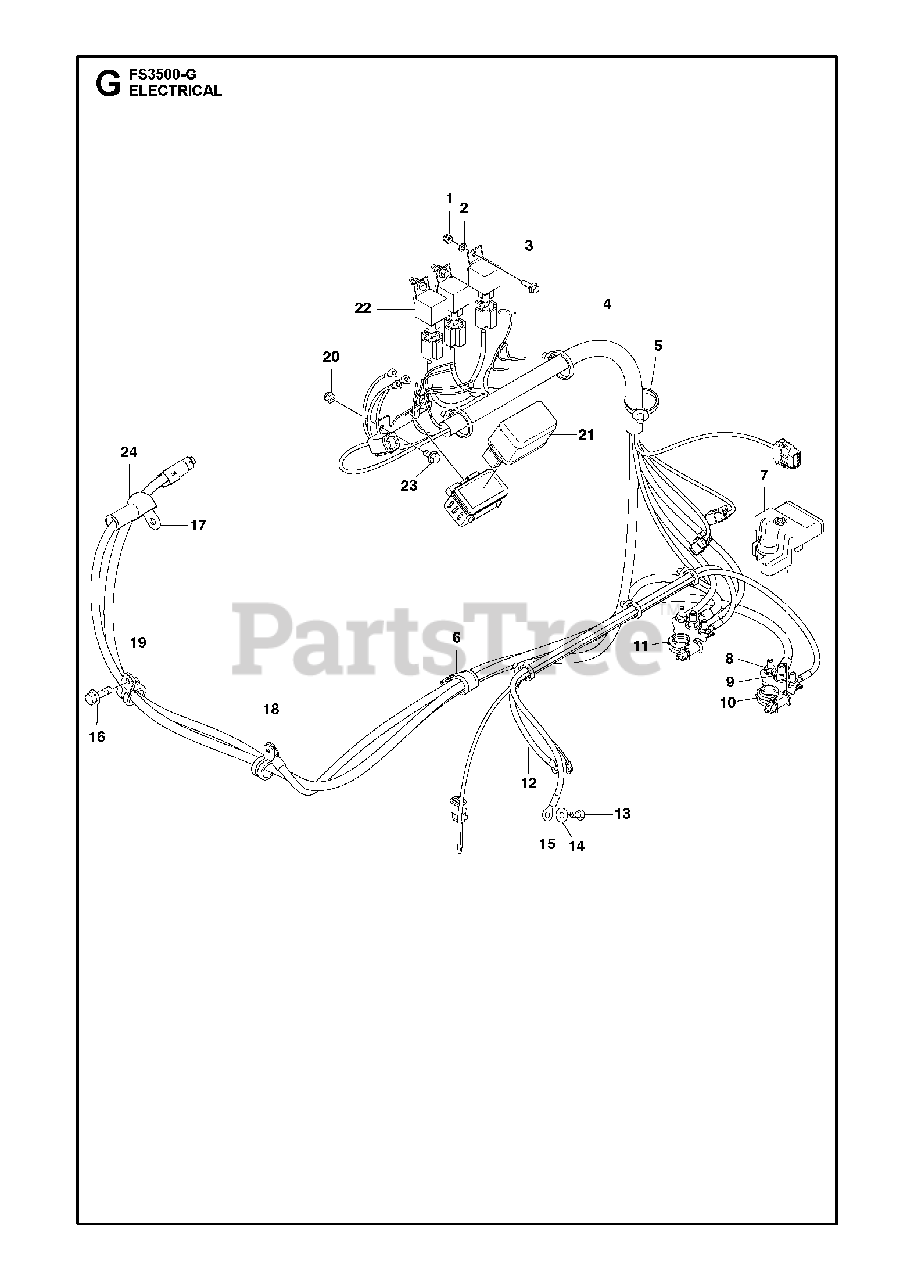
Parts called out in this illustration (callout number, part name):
1	HEXAGON LOCKING NUT
2	WASHER
8	HEXAGON NUT FLANGE
9	HEXAGON NUT FLANGE
14	WASHER 1/4 SAE
20	HEXAGON LOCKING NUT
